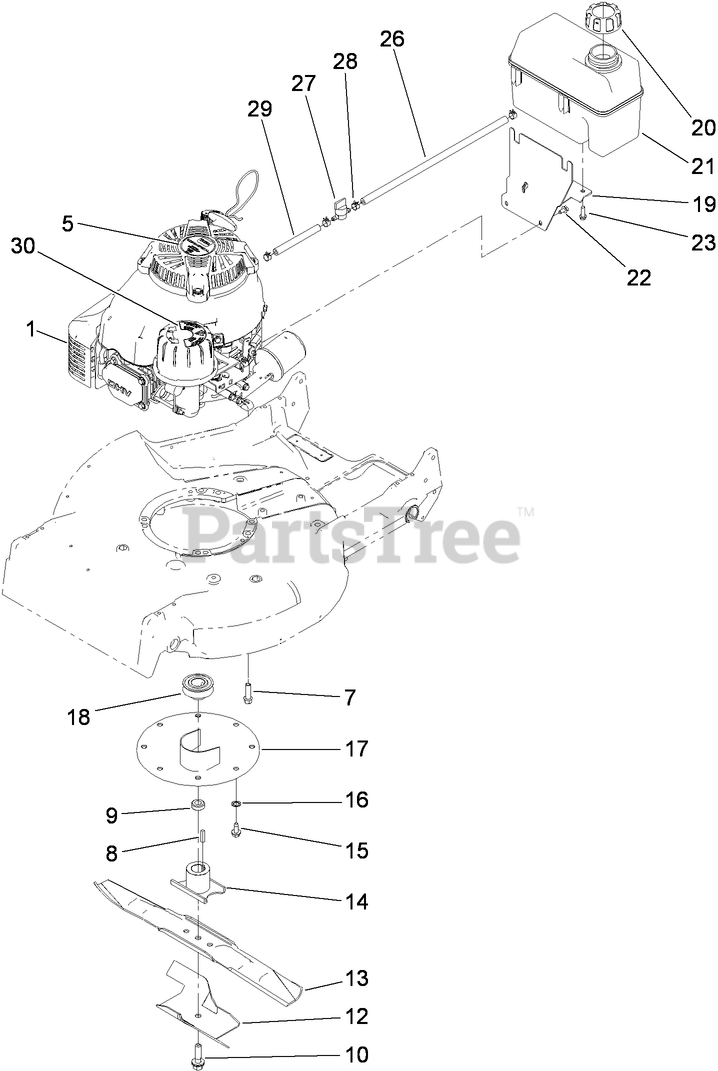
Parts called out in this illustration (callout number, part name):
7	SCREW-TAPTITE
8	KEY-SQUARE
9	SPACER-RETAINER, BLADE
12	STIFFENER-BLADE
13	BLADE-21 INCH
14	RETAINER-BLADE
15	SCREW-HWHTF
16	WASHER-LOCK, INTERNAL
18	PULLEY-DRIVER
19	MOUNT-TANK
20	CAP-GAS
21	TANK-FUEL
22	SCREW-HWH
23	SCREW-HWH
26	HOSE-FUEL
27	VALVE-FUEL
28	CLAMP-HOSE
29	HOSE-FUEL
